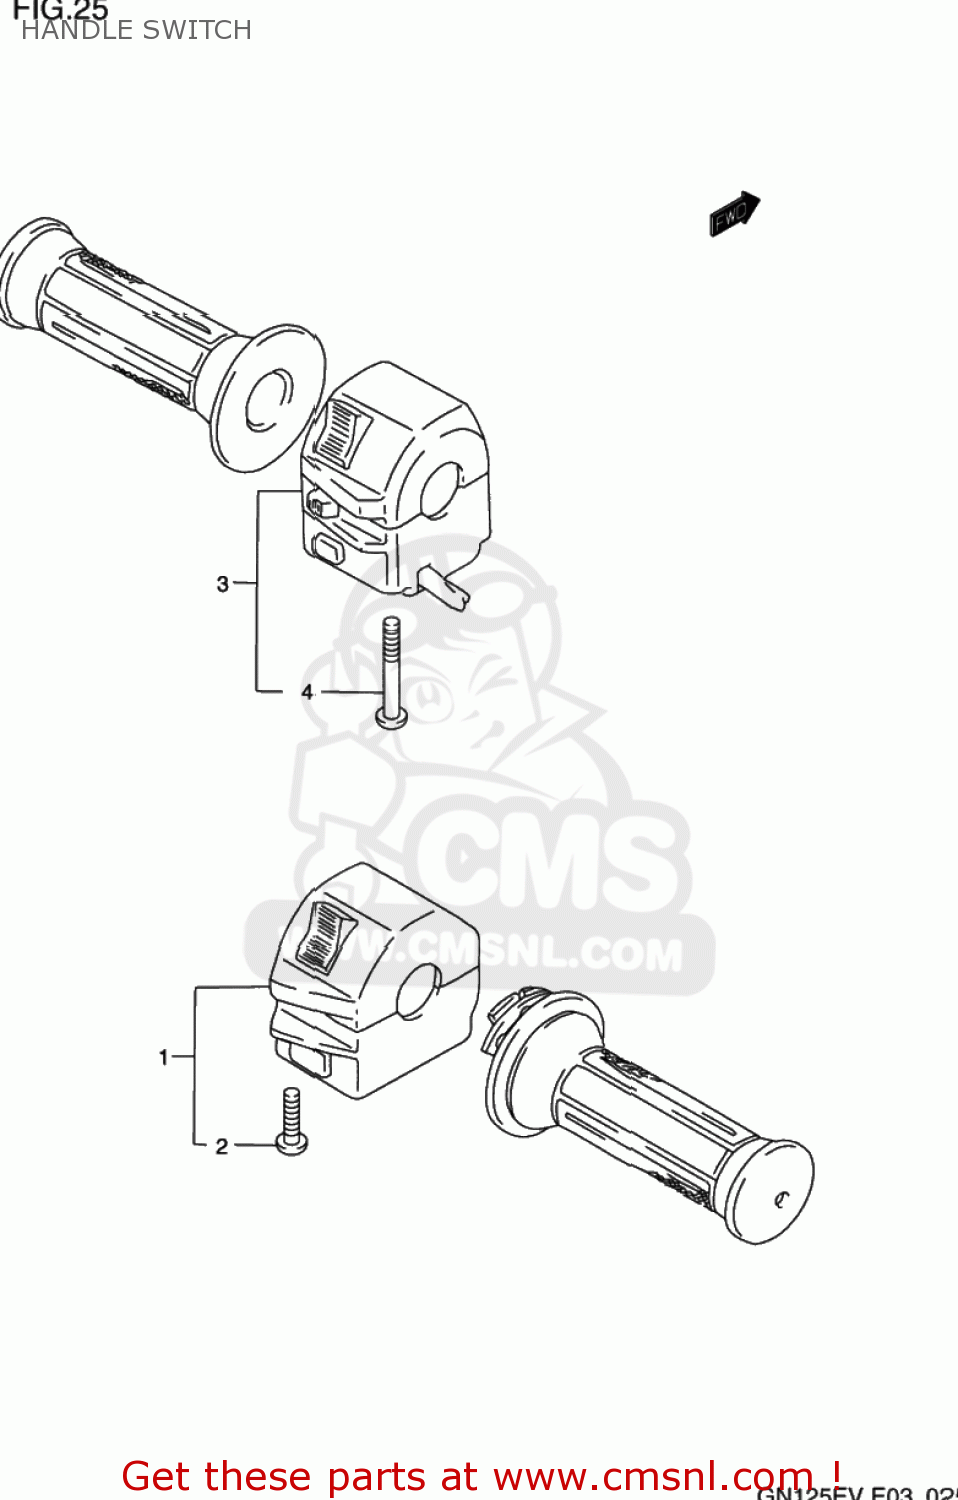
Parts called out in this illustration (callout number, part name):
1	SWITCH ASSY,HANDLE,R
2	SCREW
3	SWITCH ASSEMBLY,HANDLE,LEFT
4	SCREW
